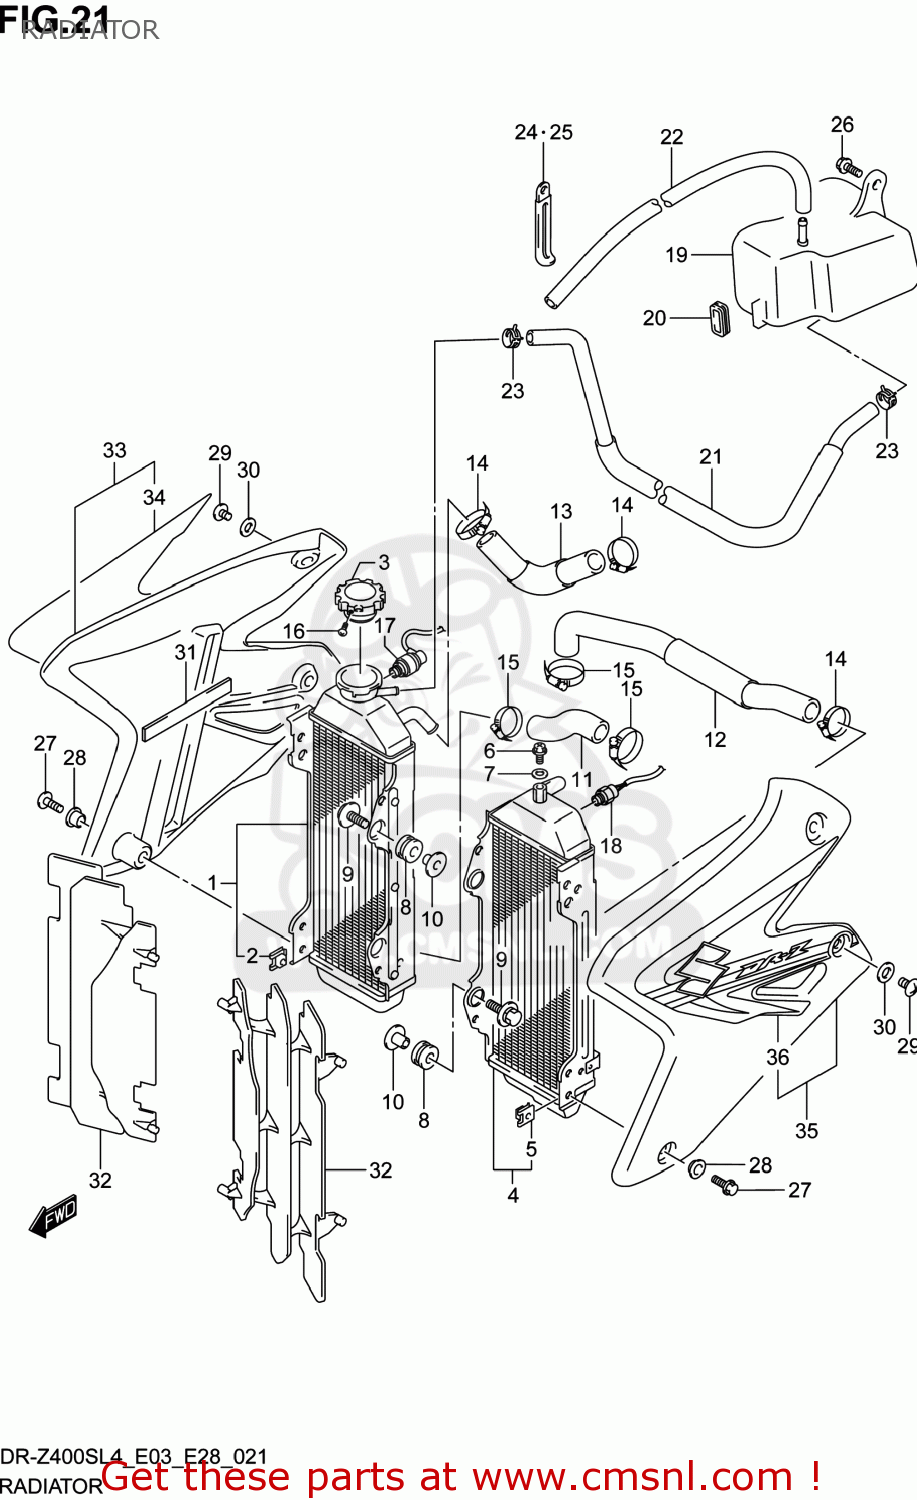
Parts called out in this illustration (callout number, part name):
1	RADIATOR,WATER,R
2	NUT
3	CAP,RADIATOR(1.1)
4	RADIATOR,WATER,L
5	NUT
6	UNION BOLT,AIR VENT
7	GASKET(6.4X11.5X0.8) (NAS)
8	CUSHION,RADIATOR LWR
9	BOLT(6X25)
10	SPACER(6.5X10.5X14.1)
11	HOSE,RADIATOR INLET
12	HOSE,RADIATOR OUTLET
13	HOSE,RADIATOR JOINT
14	CLAMP
15	CLAMP
16	SCREW,RADIATOR CAP
17	SWITCH ASSY,WATER TEMP
18	SWITCH,FAN
19	TANK,RESERVOIR
20	CUSHION,RESERVOIR TANK
21	HOSE,RESERVOIR TANK INLET
22	HOSE(5X9X2000)
23	CLIP
24	CLAMP(L:45 T:0.6)
25	CLAMP(L:45)
26	BOLT
27	BOLT(6X16)
28	WASHER
29	BOLT(6X8)
30	WASHER(6.5X14X1.6)
31	CUSHION,TOOL HOLDER
32	LOUVER,RADIATOR
33	COVER,RADIATOR,R(BLACK)
34	TAPE,RADIATOR COVER,R
35	COVER,RADIATOR,L(BLACK)
36	TAPE,RADIATOR COVER,L
